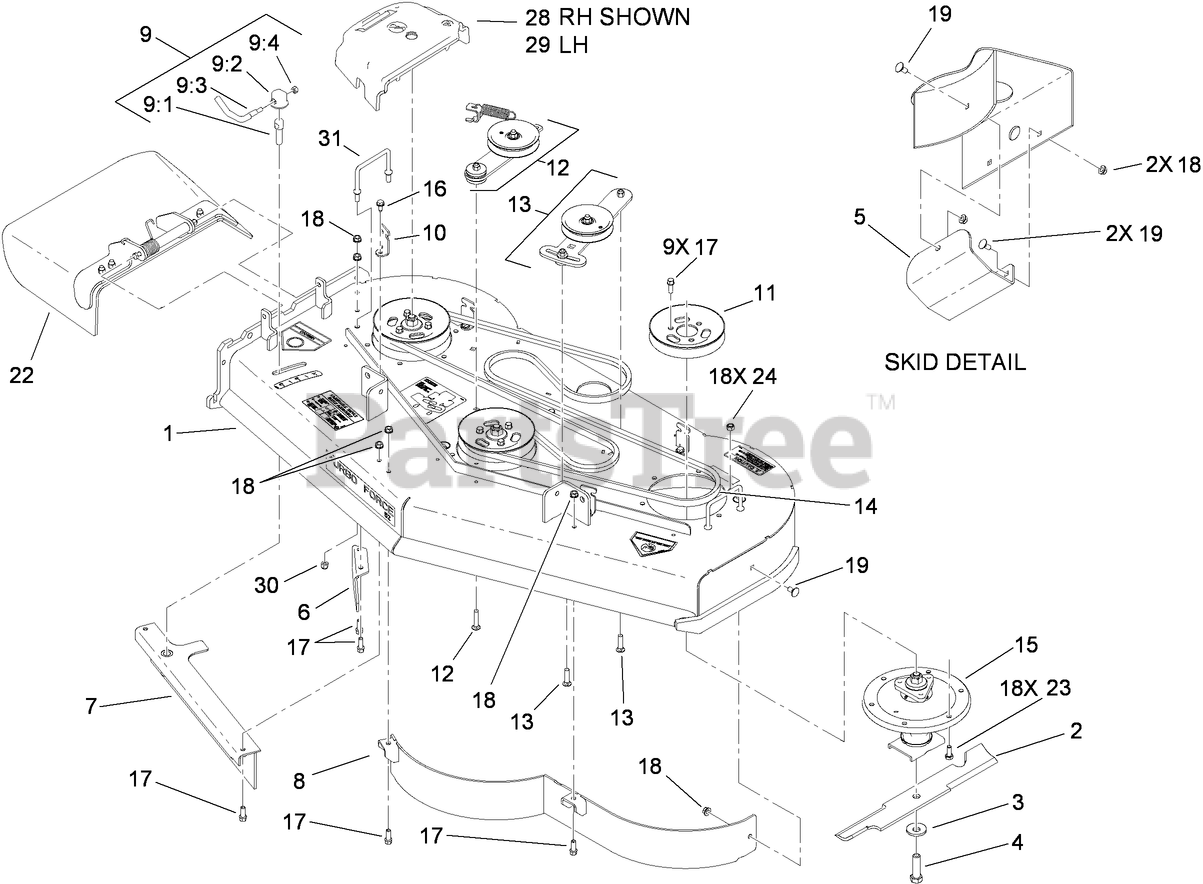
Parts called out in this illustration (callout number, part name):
1	DECK ASM
2	BLADE-18IN, HI FLOW
3	Washer-Blade Bolt, Heavy
4	Screw-Cap
6	BAFFLE-DISCHARGE
8	BAFFLE-52 INCH
9	LEVER ASM
9:1	Screw-Lock
9:2	CAP-LOCK
9:3	Lever-Lock
9:4	NUT-LOCK, NI
10	BRACKET-COVER
11	Pulley
12	SPRING IDLER ASM
13	IDLER ADJUST ASM
14	BELT-V
15	SPINDLE ASM
16	SCREW-HWHTF
17	SCREW-HWH
18	NUT-HHF, WHIZ
19	SCREW-CARR
22	DEFLECTOR ASM
23	SCREW-HH
24	NUT-LOCK, NI
28	COVER-BELT, RH
29	COVER-BELT, LH
30	NUT-LOCK, NI
31	WIREFORM-COVER
